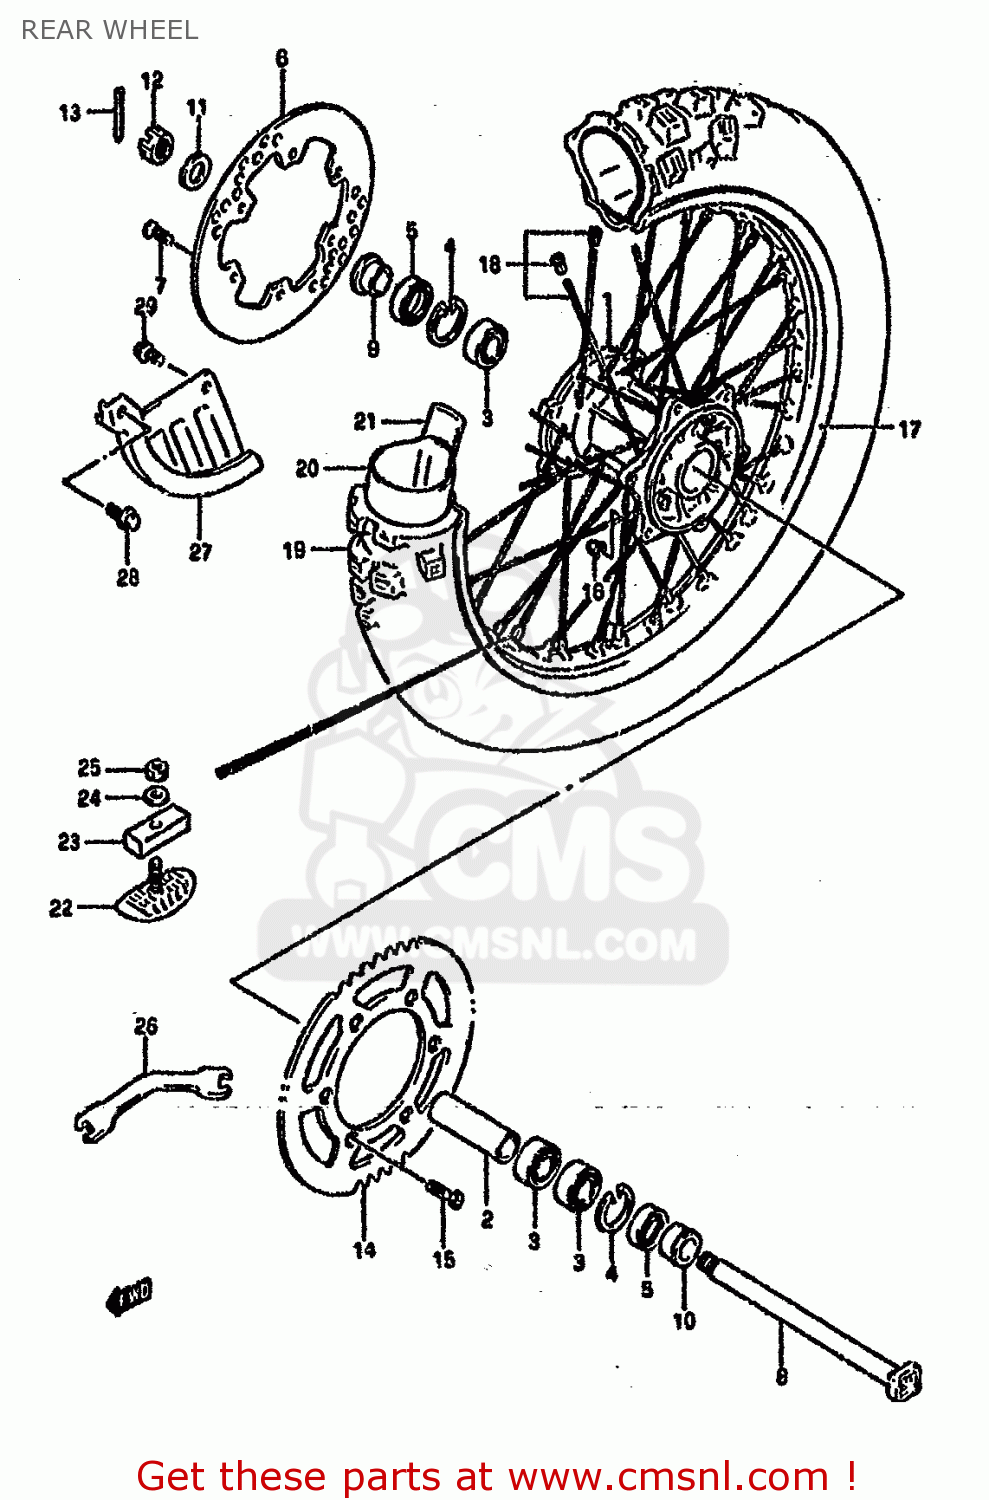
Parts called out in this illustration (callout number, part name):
1	HUB,RR WHEEL
2	SPACER,RR HUB BEARING
3	BEARING
4	CIRCLIP
5	SEAL(29X42X6)
6	DISC,REAR BRAKE
7	SCREW,BRAKE DISC
8	AXLE,RR
9	SPACER,RR AXLE,R
10	SPACER,RR AXLE
11	WASHER(19X32X3.2)
12	NUT
13	PIN,COTTER
14	SPROCKET,REAR
15	BOLT(8X30.5)
16	NUT
17	RIM,REAR WHEEL (1.85X19)(A
18	SPOKE SET,RR WHEEL
19	TIRE,REAR 100/90-19
20	TUBE ASSEMBLY,WHEEL,INNER
21	PROTECTOR,WHL INR TUBE
22	STOPPER,BEAD
23	CUSHION,BEAD STOPPER
24	WASHER
25	NUT
26	SPANNER,OPEN
27	COVER,REAR DISC
28	BOLT 6X20
29	BOLT
